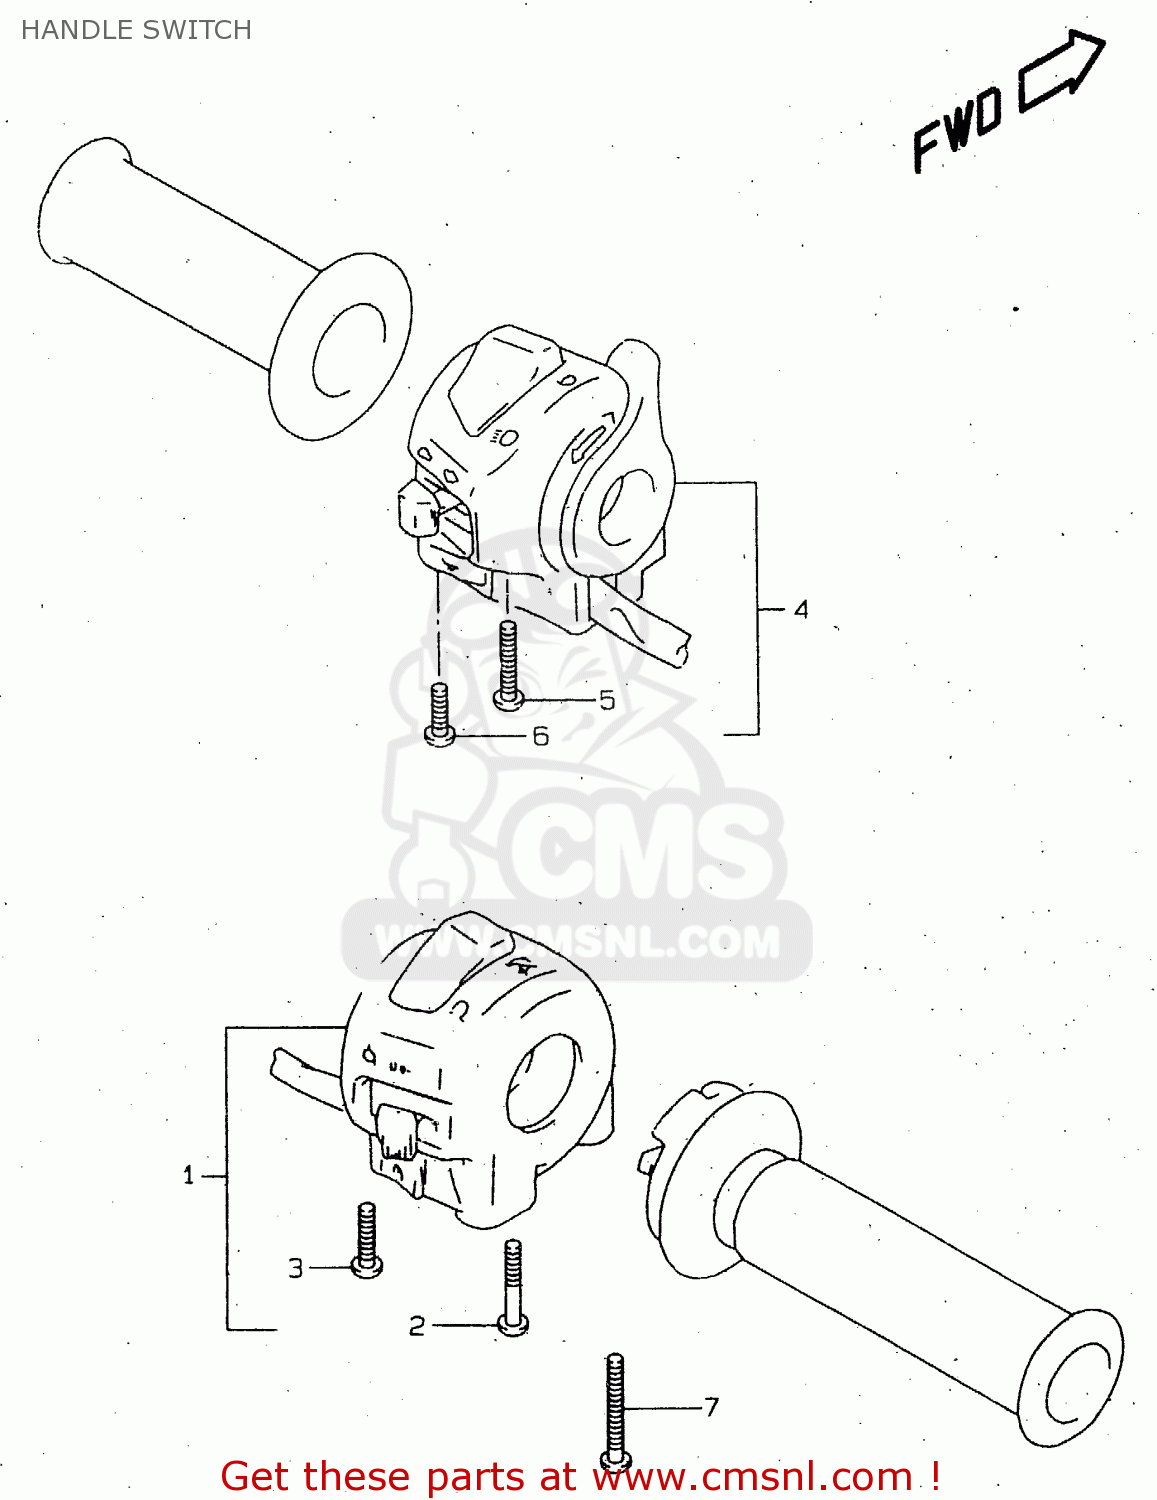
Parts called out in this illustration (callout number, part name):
1	SWITCH,HANDLE,
2	SCREW
3	SCREW
4	SWITCH ASSY,HANDLE,L
5	SCREW
6	SCREW, 5X45
7	SCREW
